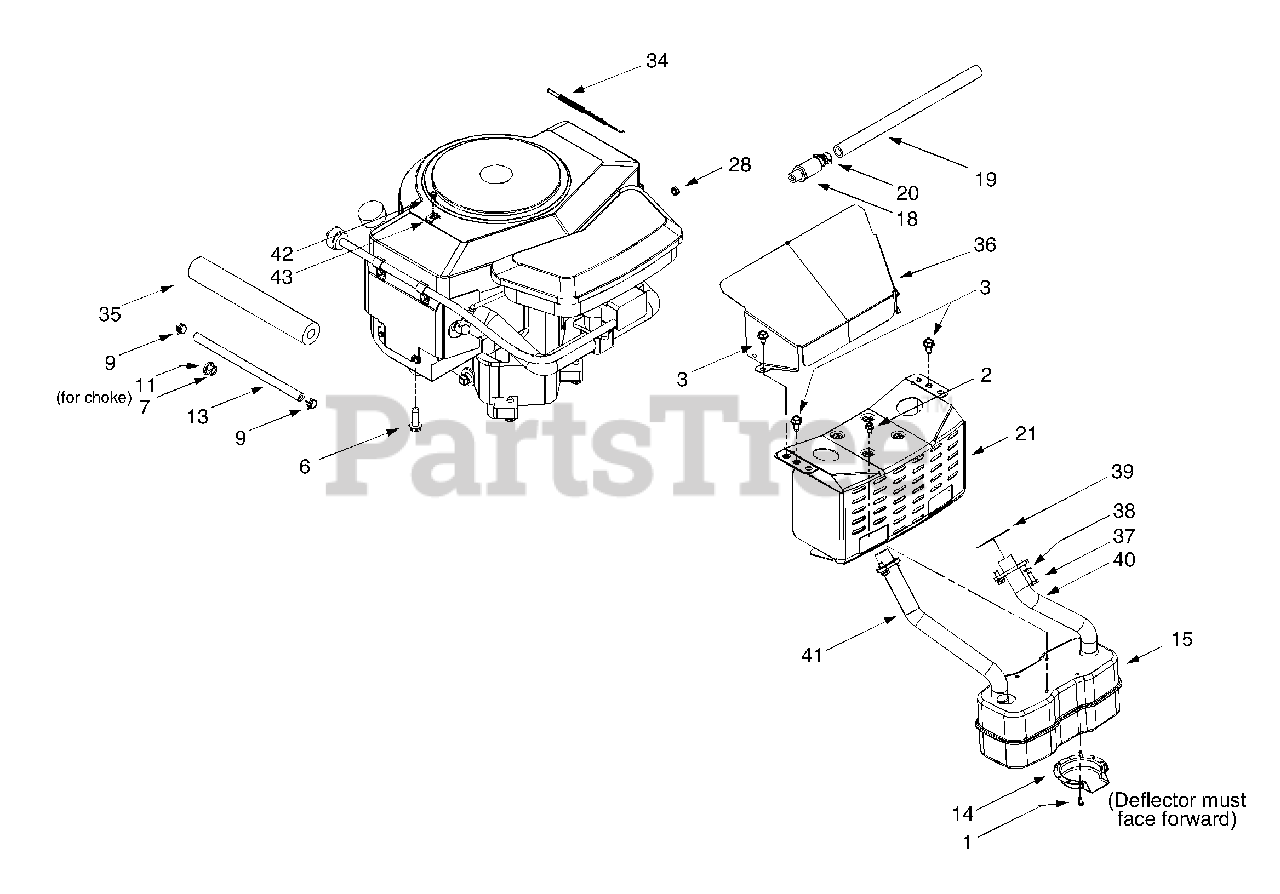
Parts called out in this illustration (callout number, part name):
1	Self-tapping Screw, #8-32 x .375
2	Self-tapping Screw, 1/4-20 x .5
3	Self-tapping Screw, 5/16-18 x .625
6	Self-tapping Screw, 3/8-16 x 1.25
7	Hex Nut, 3/8-16
9	Hose Clamp
11	Lock Washer, .406 x .875 x .059
13	Fuel Line Hose
14	Muffler Deflector
15	Muffler, Twin Inlet
18	Oil Drain Valve
19	Oil Drain Hose
20	Oil Drain Cap
28	Hex Sems Nut, 1/4-20
34	Throttle Cable
35	Foam, .625 x 1.5 x 10
37	Hex Cap Screw, 1/4-20 x .620 (Grade 5)
38	Lock Washer, 1/4
39	Exhaust Gasket
40	LH Exhaust Pipe
41	RH Exhaust Pipe
42	Screw, #10-16 x .5
43	Clamp, 9/16
